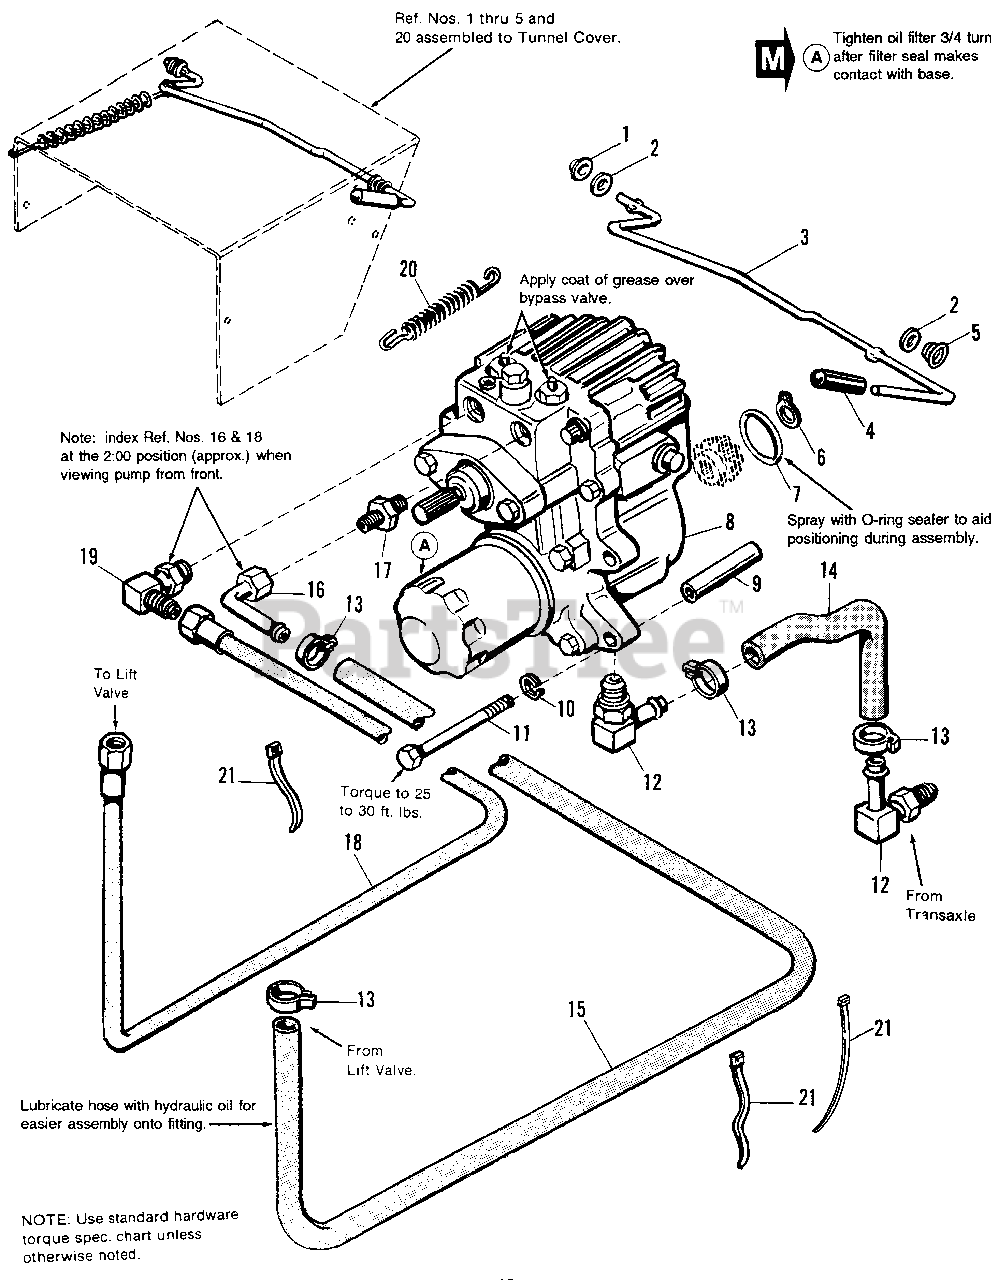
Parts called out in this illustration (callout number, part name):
1	PUSH NUT, 1/4
2	WASHER, 17/64 X 5/8 x 3/64
3	ROD, Hydrostatic Release
4	GRIP, Release Handle
6	RING, Retaining Ext. (.688 Shaft I.D., Early Models)
6	RING, Retaining Ext. (.625 Shaft I.D., Later Models)
8	HYDROSTATIC PUMP (See page 44 for parts breakdown.)
9	SPACER, Mounting
10	LOCKWASHER, 3/8
11	CAPSCREW, Hex Hd., 3/8-16 x 4
12	FITTING, HYD., 7/8-14 O.R. x 5/8 90
13	CLAMP, Hose
14	HOSE, HYD., 5/8 Preformed
15	HOSE, Hyd., Return (Cooler to Pump)
16	ELBOW, 90 Barb 3/4-16 x 1/2
17	FITTING, Hyd., 9/16-18 O.R. x 3/4-16 St. Flare
19	ELBOW, Hyd. Male Swivel, 9/16-18 O.R. x 9/16-18
20	SPRING, Tension, Hydrostatic Release
21	TIE, Self-Locking
